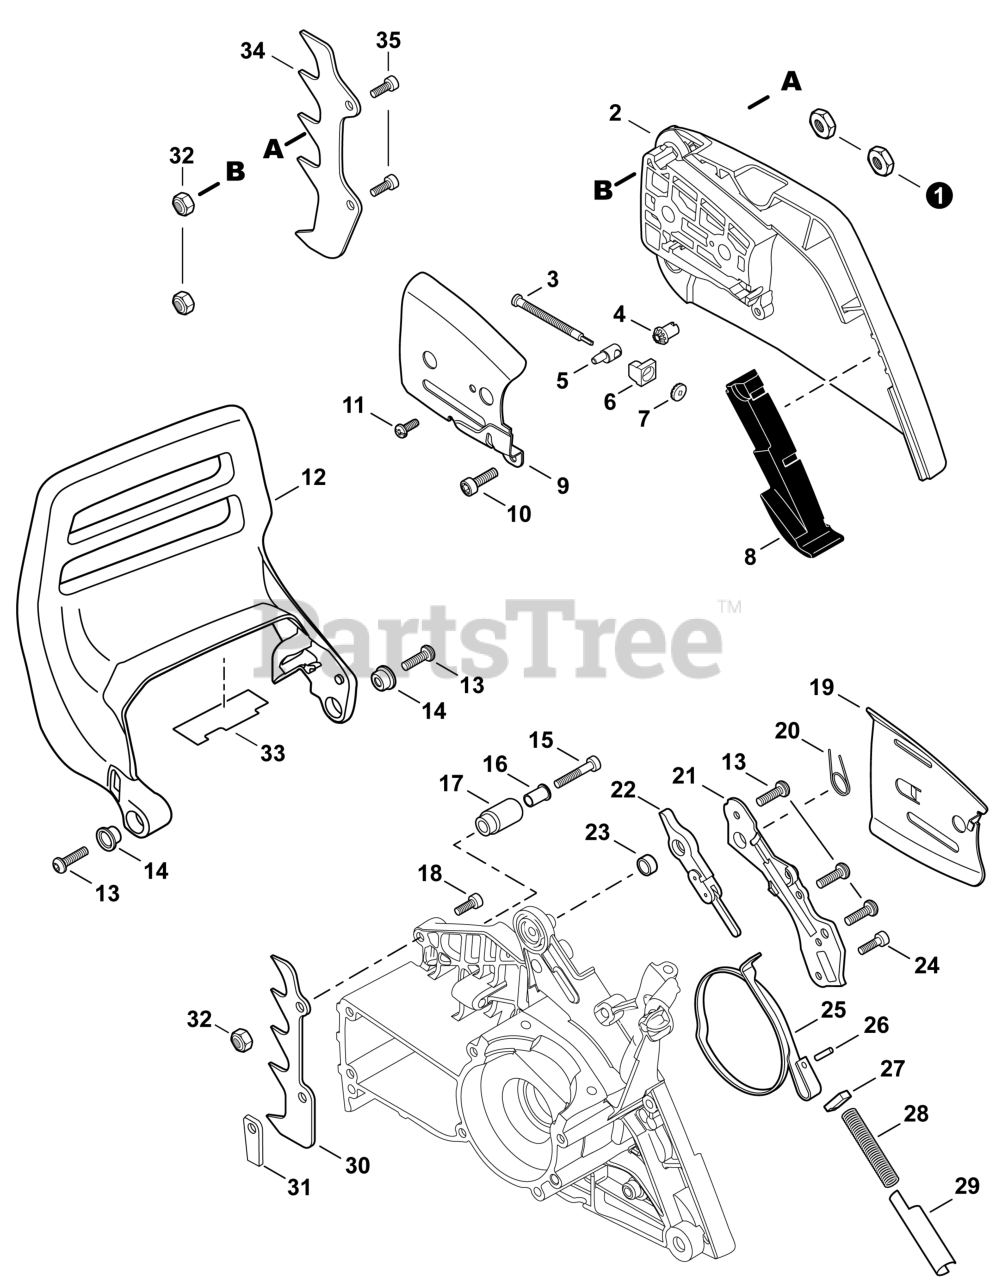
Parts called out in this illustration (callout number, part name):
2	GUARD, SPROCKET
3	SCREW, CHAIN TENSION 63 MM
4	GEAR, BEVEL
5	TENSIONER, CHAIN
6	COLLAR 8
7	GEAR, BEVEL
8	CUSHION
9	PLATE, GUIDE - OUTER
10	BOLT, TORX 4×12
11	SCREW 3×5
12	LEVER, BRAKE
13	BOLT, TORX 5×16
14	COLLAR 11.2×16.2×T0.6
15	BOLT, TORX 5×35
16	COLLAR 5
17	CHAIN CATCHER
18	BOLT, TORX 5×16
19	PLATE, GUIDE - INNER
20	SPRING, TORSION
21	COVER, BRAKE
22	CONNECTOR, BRAKE
23	SPACER 12×10×T: 1.0
24	BOLT, TORX 4×12
25	BAND, BRAKE
26	PIN, SPRING 3×9.8
28	SPRING, COMPRESSION Ø12×70.5
29	PLATE, SIDE
30	SPIKE, BUMPER
32	NUT, LOCK M5
33	SHIELD, HEAT 75×27×0.15
34	SPIKE, BUMPER
35	BOLT, TORX 5×12
